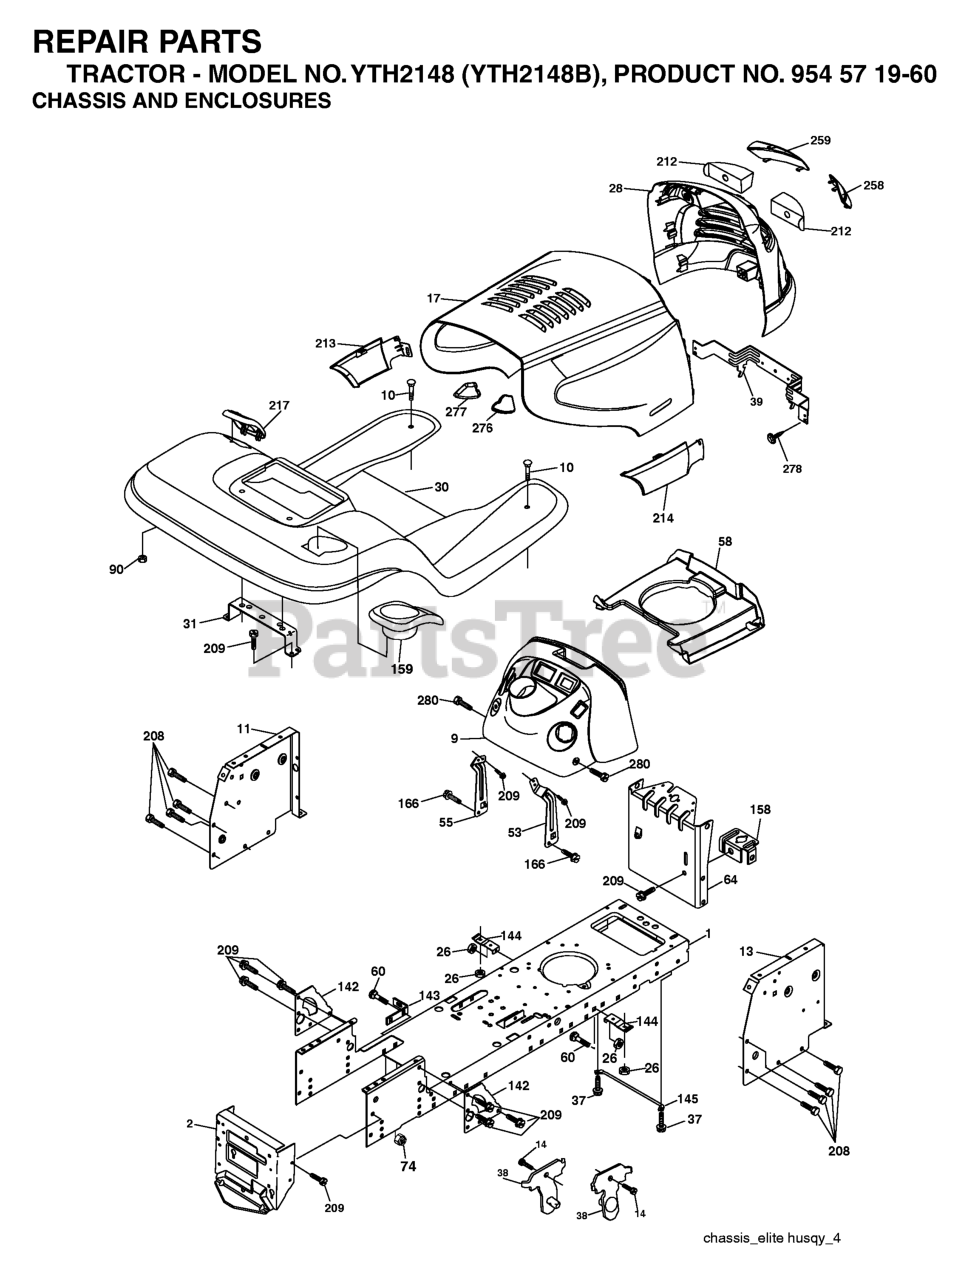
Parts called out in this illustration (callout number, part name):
1	CHASSIS STAMPING
2	DRAWBAR, 12GA
10	BOLT D
11	PANEL.DASH.LH.LTX
13	PANEL DASH RH
26	NUT
30	FENDER STL W/CUPHOLDER
31	BRACKET.SUPPORT.FENDER
37	Screw 5/16-18 x 1/2 Hex, Self Tapping 5/16-18 x 1/2
38	BRACKET.ASM.PIVOT.MOWER.REAR
39	BRACKET PIVOT LASER
60	Bolt - Rd. Hd. Sq. Neckiage 3/8 16 x 3/4
64	DASH LOWER
90	NUT.PUSH.3/16
142	PLATE REINFORCEMENT
143	BRACKET, SWAYBAR CHASSIS
144	BRKT, FOOT REST
145	ROD PIVOT CHASSIS/HOOD
158	BRACKET PARKING BRAKE
159	GREY CUP HOLDER
166	SCREW
208	SCREW 3/8-16X1/2
209	SCREW, 3/8-16X3/4
217	CONSOLE FUEL WINDOW
278	SCREW
280	SCREW 3/8-16X1
